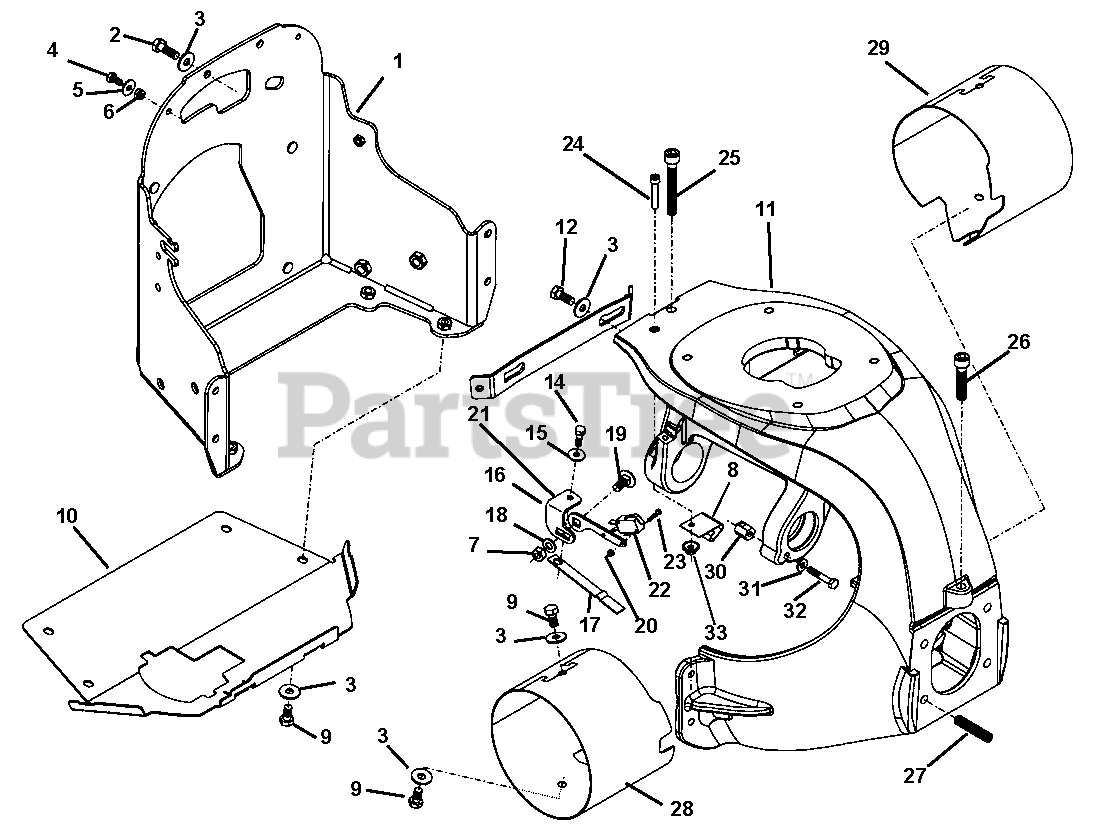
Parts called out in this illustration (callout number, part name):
1	Bracket, Engine
2	Bolt, Hex D933 M8 x 25
3	Washer, M8
4	Bolt, Hex D933 M6 x 12
5	Washer, D9021 6.3 x 18
6	Nut, Lock D985 M6
7	Nut, Hex D934 M8
8	Spring, Lock
9	Bolt, Hex D933 M8 x 16
12	Bolt, Hex D933 M8 x 20
14	Bolt, Hex D933 M6 x 18
15	Washer, M6
17	Lever, Spring
18	Washer, M8
19	Truss Head Screw, D603 M8 x 20
20	Nut, Lock D985 M3
21	Plate, Lock
22	Safety Switch, PTO Position
23	Screw, Flat Head D85A M3 x 18
24	Bolt, Cylindrical D912 M6 x 35
25	Screw, D912 M10 x 70
26	Screw, D912 M10 x 45
27	Screw, Set D913 M10 x 50
28	Guard, Grass Right Hand
29	Guard, Grass Left Hand
30	Support, Cable
31	Washer, M6
32	Screw, D933 Metric 6 x 35
33	Nut, Flanged M6
